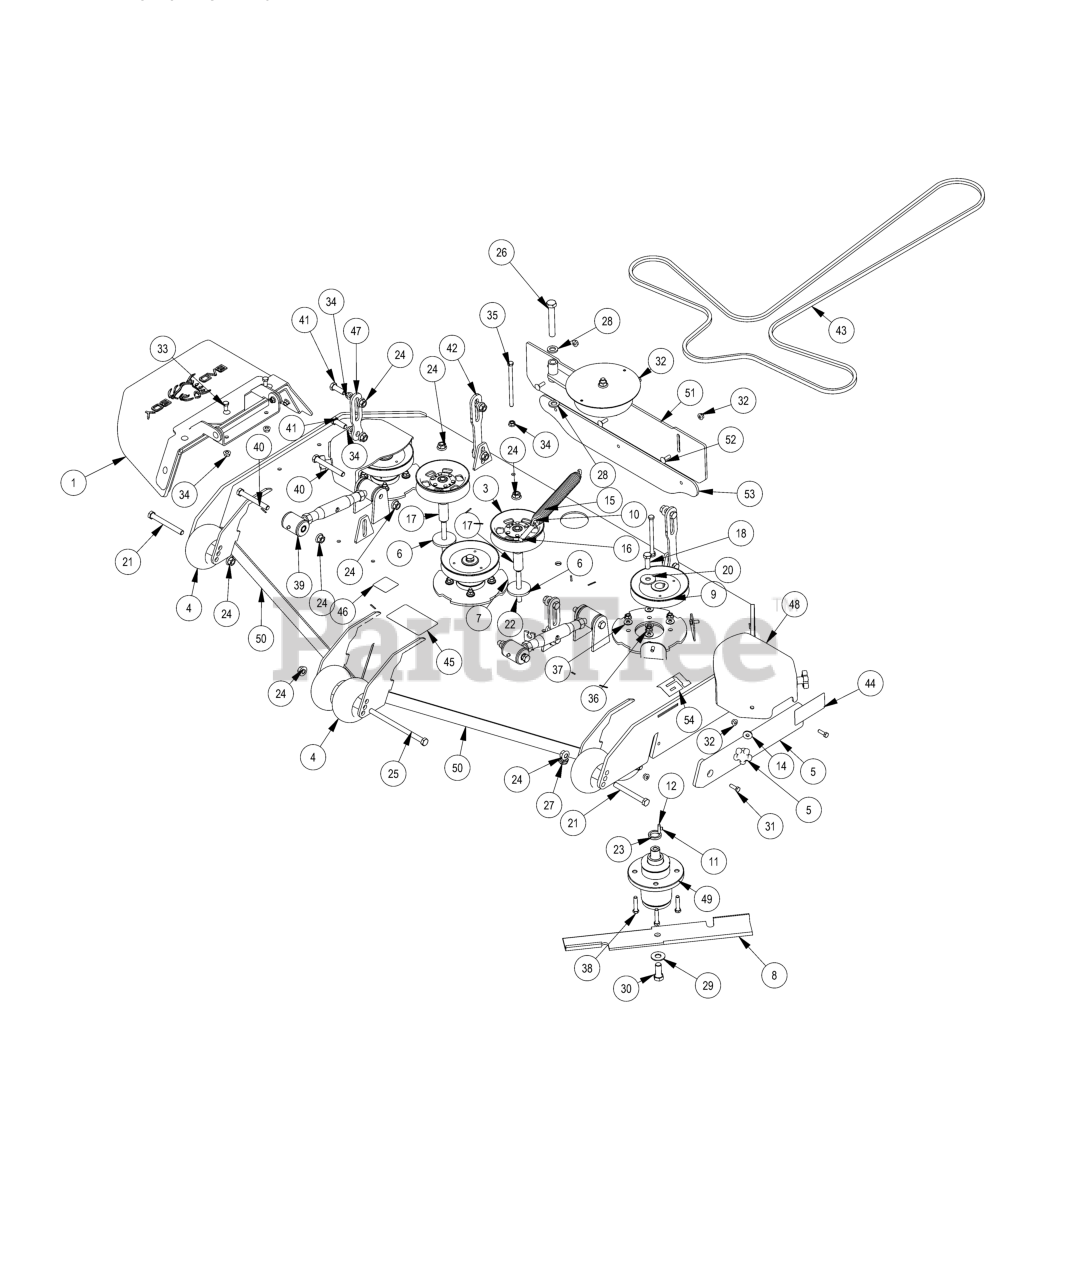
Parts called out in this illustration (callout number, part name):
1	2019 Outlaw Gen2 Chute Assembly
2	2020 61 Revolt Deck Idler Assembly
3	5-3/4 Idler Pulley
4	2019 Deck Wheel
5	REVISED TRIM BUMPER_20180226
6	MZ Deck Idler Spacer
7	Deck Spindle Support Plate
8	61 inch Fusion Blade
9	6 1/4" Drive Pulley
10	2019 Outlaw Gen2 Deck Spring
11	5/16-24 X 1/4 SOCKET SET SCREW (CUP PT) PLAIN
12	1/4 X 1 SQ MACHINERY KEY 1018 STL PLN
13	5/16" Knob
14	.360 ID X .983 OD X .120 THICK FLAT WASHER NYLON BLACK
15	1/2-13 HEX NUT ZINC
16	All Thread
17	2019 Revolt Stationary Idle Spacer
18	1/2-20 X 1-1/2 HEX CAP SCREW (GR.5) ZINC
19	1/2 SPLIT LOCKWASHER (GR.8) ZINC/YELLOW
20	1/2 BELLEVILLE WASHER (1-5/8 OD X .140 THK) ZINC
21	1/2-13 X 4-1/2 HEX CAP SCREW (GR.5) ZINC
22	1/2-13 X 4-1/4 HEX CAP SCREW (GR.5) ZINC
23	1.02 ID X 1.38 OD X .250 THK SPACER ZINC
24	1/2-13 NYLON INSERT FLANGE LOCKNUT ZINC
25	1/2-13 X 8 HEX CAP SCREW GR 5 ZINC
26	5/8-11 X 4 HEX CAP SCREW (GR.8) ZINC YELLOW
27	5/8-11 NYLON INSERT JAM LOCKNUT ZINC
28	.635 ID X 1.120 OD X .140 THICK FLAT WASHER NYLON
29	5/8 USS FLAT WASHER (1-3/4" OD) GR.8 ZINC YELLOW
30	5/8-18 X 1-1/2 HEX CAP SCREW (GR.8) ZINC YELLOW
31	5/16-18 X 1 HEX CAP SCREW (GR.5) ZINC
32	5/16-18 NYLON INSERT FLANGE LOCKNUT ZINC
33	3/8-16 X 3/4 HEX CAP SCREW (GR.5) ZINC
34	3/8-16 HEX SERRATED FLANGE NUT HARD/ZINC
35	3/8-16 X 5-1/2 HEX CAP SCREW (GR.5) ZINC
36	3/8-16 NYLON INSERT FLANGE LOCKNUT (GR.F) ZINC
37	5/16 USS FLAT WASHER (7/8 OD) ZINC
38	3/8-16 X 1-3/4 HEX C/S (GR.5) ZC
39	Turnbuckle
40	1/2-13 X 4 HEX CAP SCREW (GR.8) ZINC YELLOW
41	1/2-13 X 1-1/2 HEX CAP SCREW (GR.5) ZINC
42	2023 Stand-On Rear Deck HangerV2
44	Danger Decal-Spindle/Discharge
45	2019 Revolt Deck Belt Route Decal
46	Deck Impact Patent Decal 9591803
47	2023 revolt 61 front hanger V2
48	2023 Revolt pulley cover
49	OUTLAW SPINDLE ASSEMBLY
50	2023 61'' DECK
51	2023 MZ Stripping Kit Rubber
52	5/16-18 X 1 CARRIAGE BOLT (GR.8) ZINC
53	Striping Kit Plate
54	61" Deck Decal
